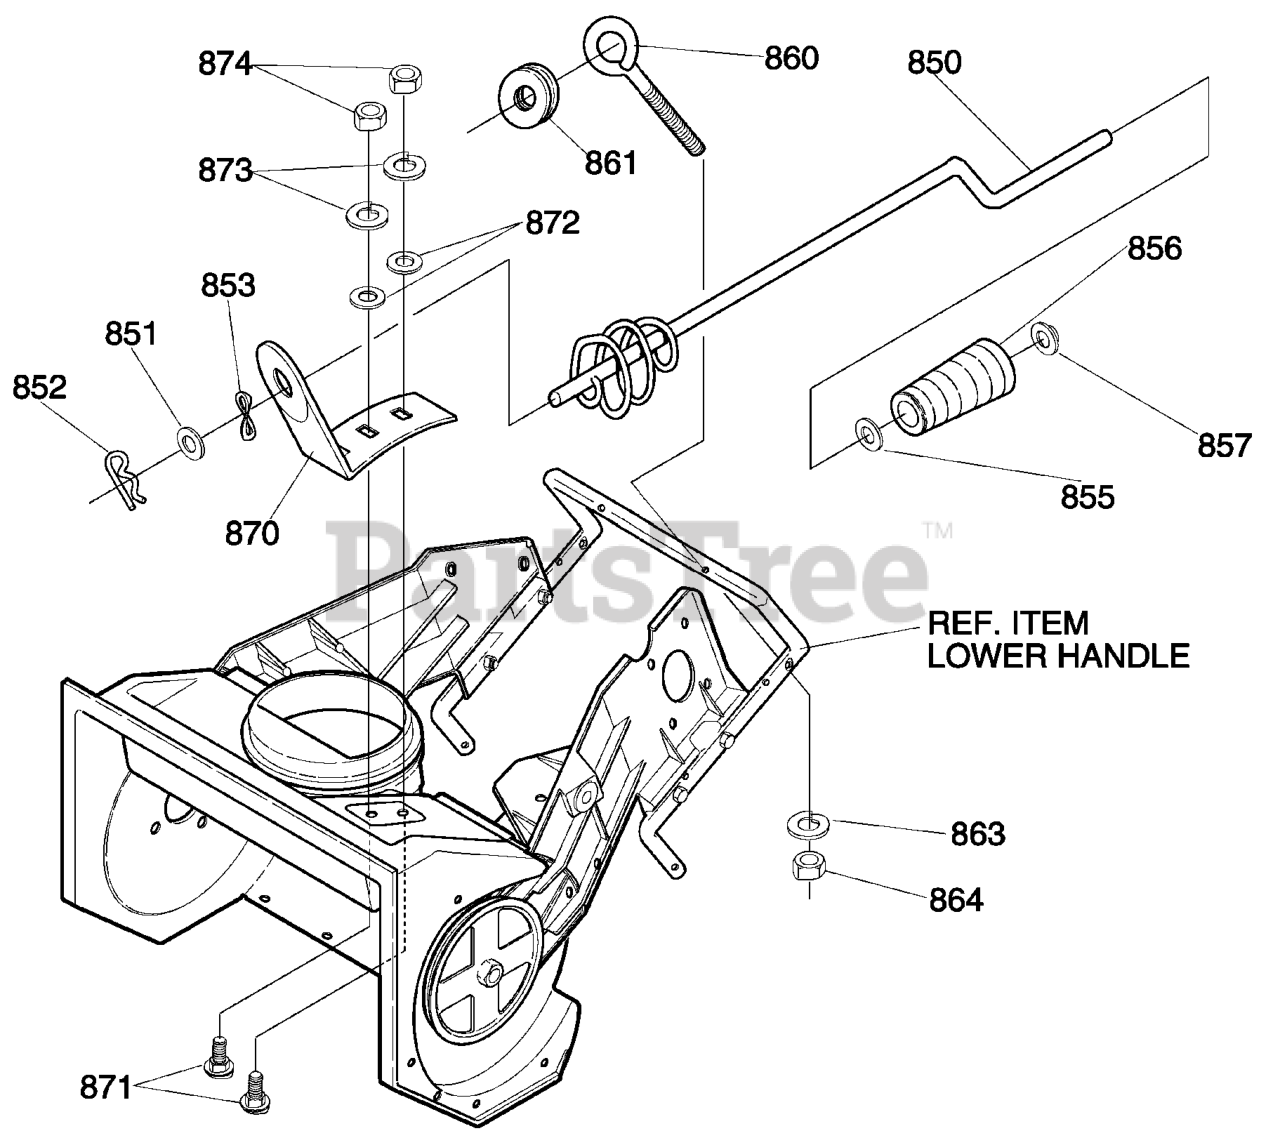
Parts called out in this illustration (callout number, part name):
850	ROD, ASSY UPPER CHUTE
851	FLATWASHER
852	COTTER PIN
853	WASHER, CURVED SPRING
855	FLATWASHER
856	KNOB, SLEEVE
857	NUT, PUSH
860	EYE BOLT 3/8-16x2.00
861	GROMMET, EYE BOLT
863	WASHER, SPLITLOCK
864	NUT, 3/8-16
870	BRACKET, CHUTE ROTATE
871	BOLT, 5/16-18 x .75
872	FLATWASHER
873	WASHER, SPTLOCK
874	NUT, 5/16-18
